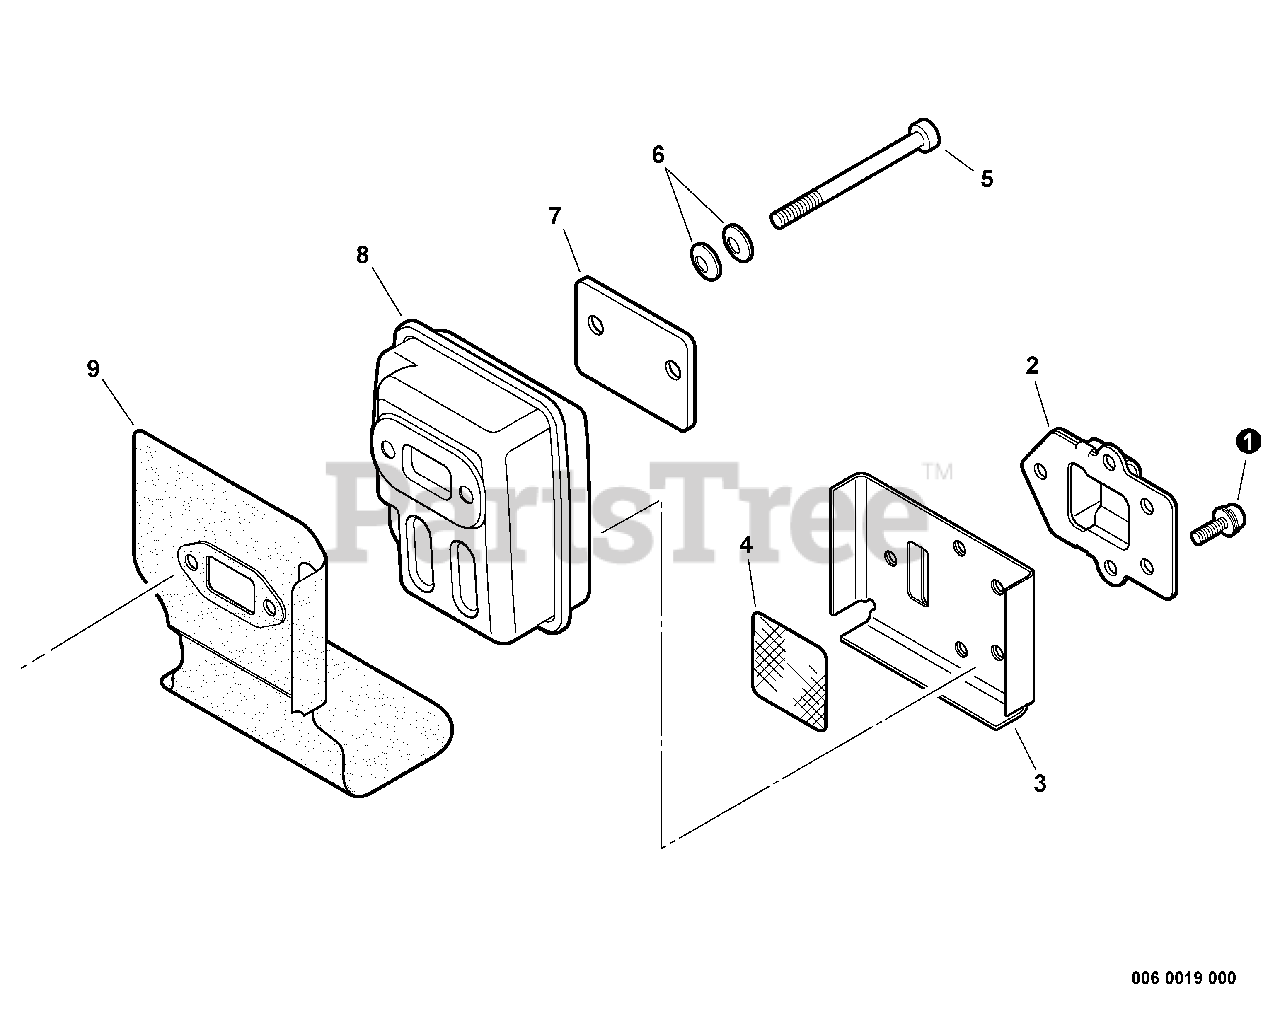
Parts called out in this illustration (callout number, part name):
1	SCREW 4×10
2	GUIDE, EXHAUST
3	GASKET, EXHAUST
4	SCREEN, SPARK ARRESTER
5	BOLT 5×55
6	CONICAL WASHER
7	PLATE, EYE
8	MUFFLER
9	HEAT SHIELD, EXHAUST
